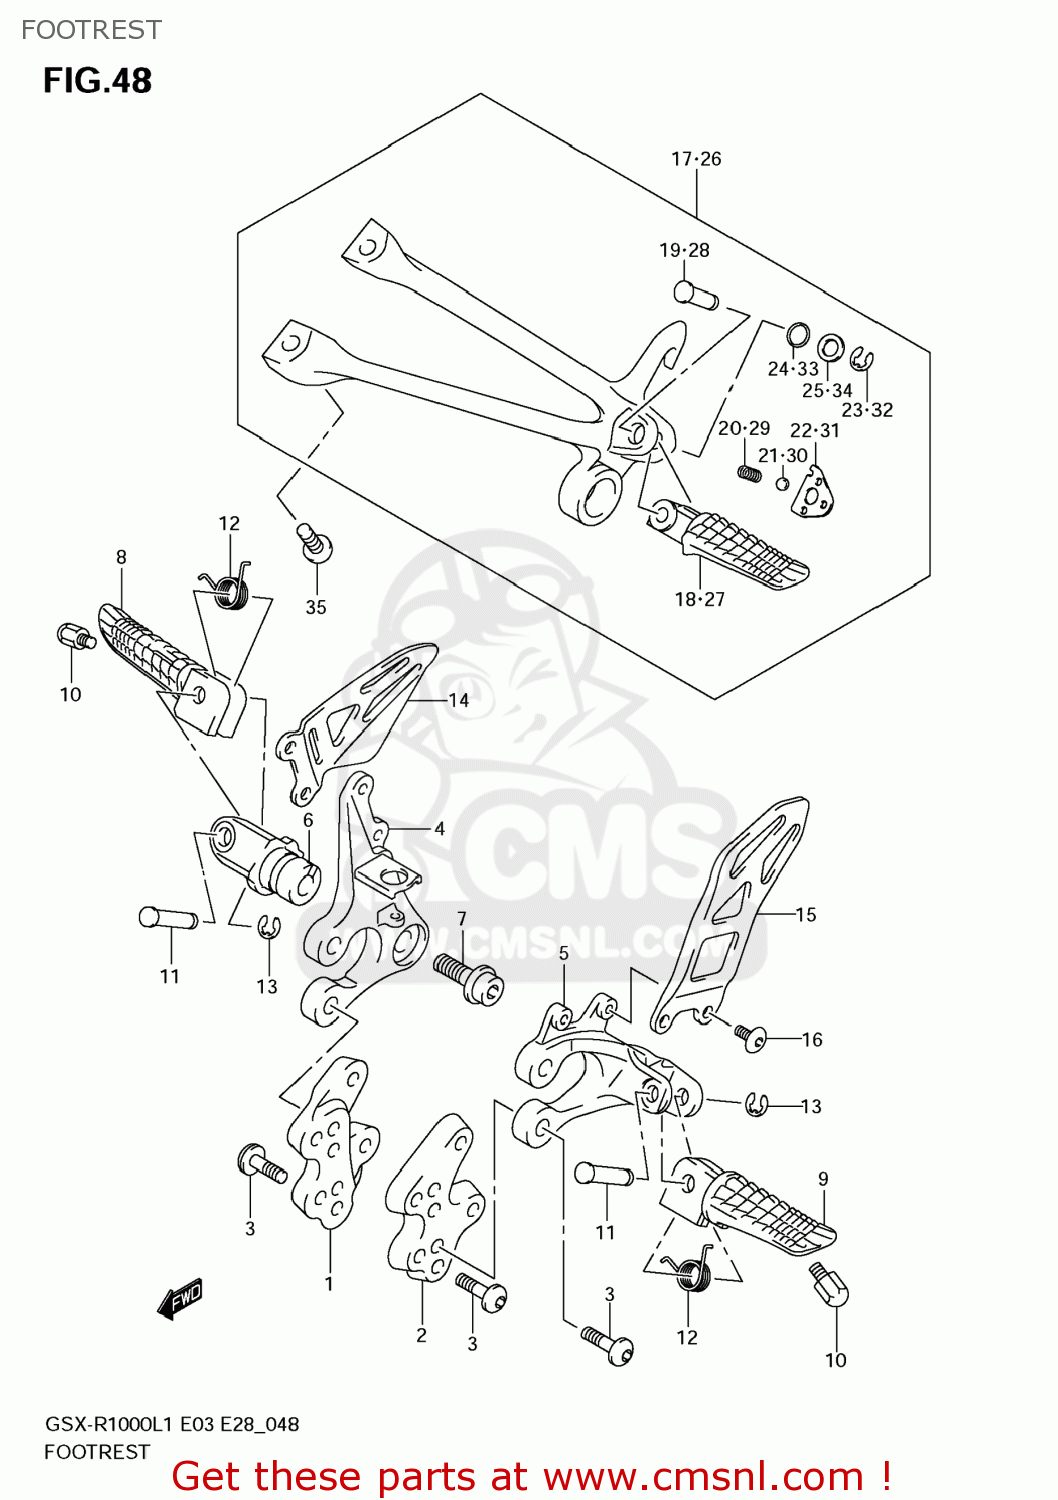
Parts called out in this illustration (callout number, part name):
1	BRACKET,FR FOOTREST NO.1,R
2	BRACKET,FR FOOTREST NO.1,L
3	BOLT(8X23)
4	BRACKET,FR FOOTREST NO.2,R
5	BRACKET,FR FOO
6	HOLDER,FOOTREST
7	BOLT(10X28)
8	BAR,FR FOOTREST,R
9	BAR,FR FOOTREST,L
10	BOLT,BANK SENSOR
11	PIN(8X33.2)
12	SPRING
13	E RING
14	GUARD,FR FOOTREST,R
15	GUARD,FR FOOTR
16	SCREW,FOOTREST GUARD,L
17	FOOTREST ASSY,PILLION,R
18	BAR,PILLION FOOTREST,R
19	PIN
20	SPRING
21	BALL
22	PLATE,PILLION FOOTREST,R
23	E RING
24	O RING(D:2.4,ID:6.9)
25	WASHER(8.5X14X1.0)
26	FOOTREST ASSY,PILLION,L
27	BAR,PILLION FOOTREST,L
28	PIN
29	SPRING
30	BALL
31	PLATE,PILLION FOOTREST,L
32	E RING
33	O RING(D:2.4,ID:6.9)
34	WASHER(8.5X14X1.0)
35	BOLT(8X23)
